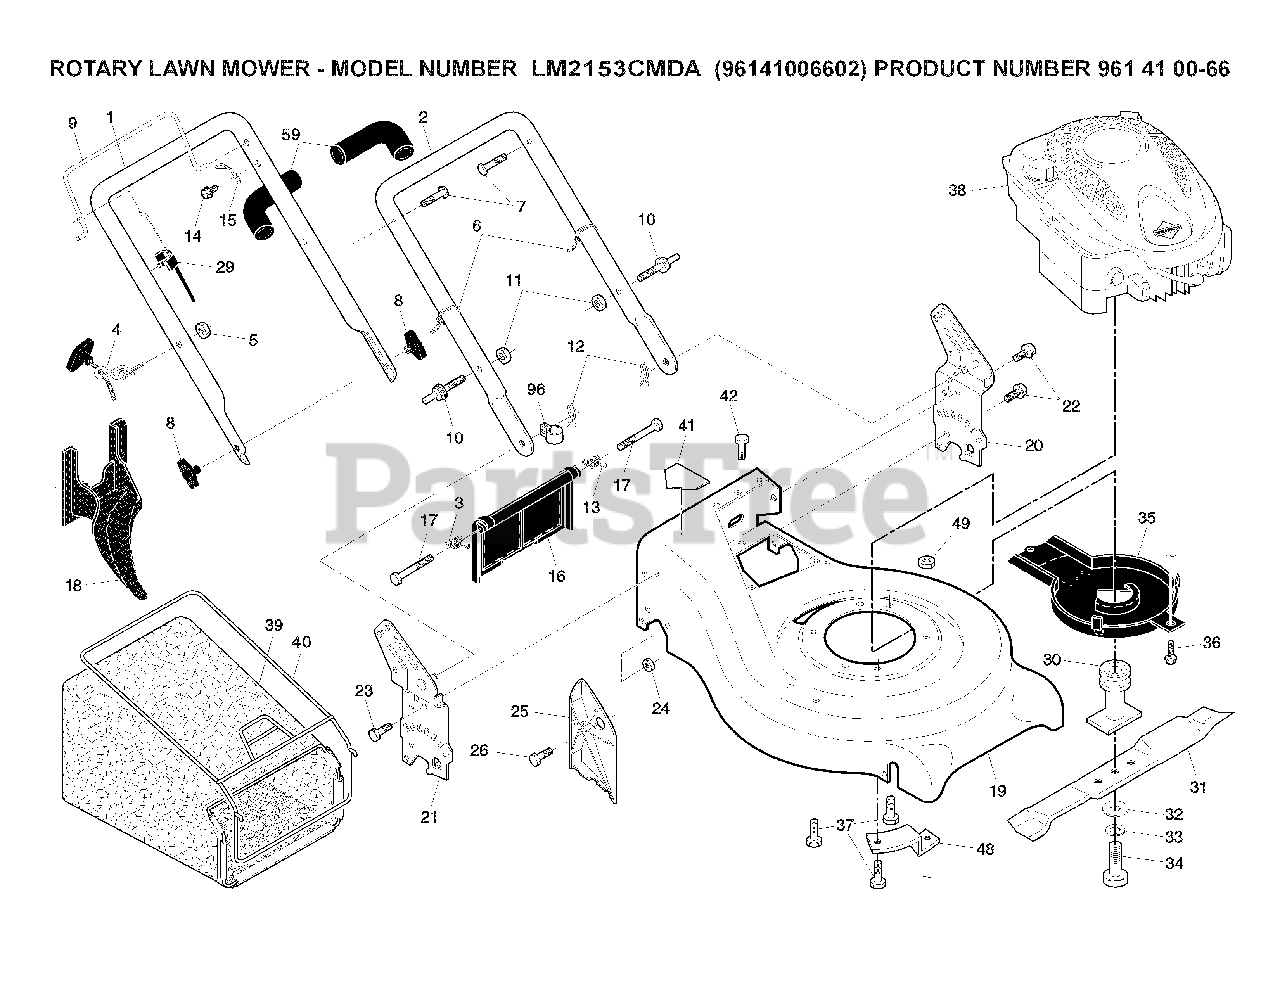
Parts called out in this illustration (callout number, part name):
2	HANDLE LOWER
3	SPRING.RH.REAR.DOOR.21.RWGD
4	GUIDE.ROPE.STD.BLK.ZIN
5	NUT
6	TIE GUIDE
7	BOLT, HANDLE 5/16-18X1.75
8	KNOB, DEFLECTOR
11	NUT, LOCK 5/16-18
12	HAIRPIN COTTER
13	SPRING.LH.REAR.DOOR.21.RWGD
15	BRACKET UPSTOP
16	REAR DOOR ASSEMBLY
18	PLUG.MULCHER.RGD.21.
20	BRKT.ASM HNDL
21	BRKT.ASM.HNDL
22	SELF-TAPPING SCREW 5/16-18X3/4
23	BOLT, HEX HEAD 5/16-18
24	NUT.71038.31-18.HEX.NYLOCK
25	CLIPPING DEFLECTOR
29	SNAP-ON.ZONE.CABLE.ASS
30	BLADE ADAPTOR / PULLEY
31	BLADE.21.PUSH
32	WASHER,HARDEN
33	LOCKWASHER
34	SCREW, HEX HD 3/8-24 X 1-3/8
35	DEBRIS SHIELD
36	SCREW.HEX.WSH
37	BOLT 3/8-16X1-1/8
40	FRAME, GRASSBAG
41	DECAL.INTERNATIONL.CUTFINGER
48	BRACKET
59	GRIP.HANDLE.FOAM.WIDE.(1 SIDE)
96	CLIP.CABLE.BLK
